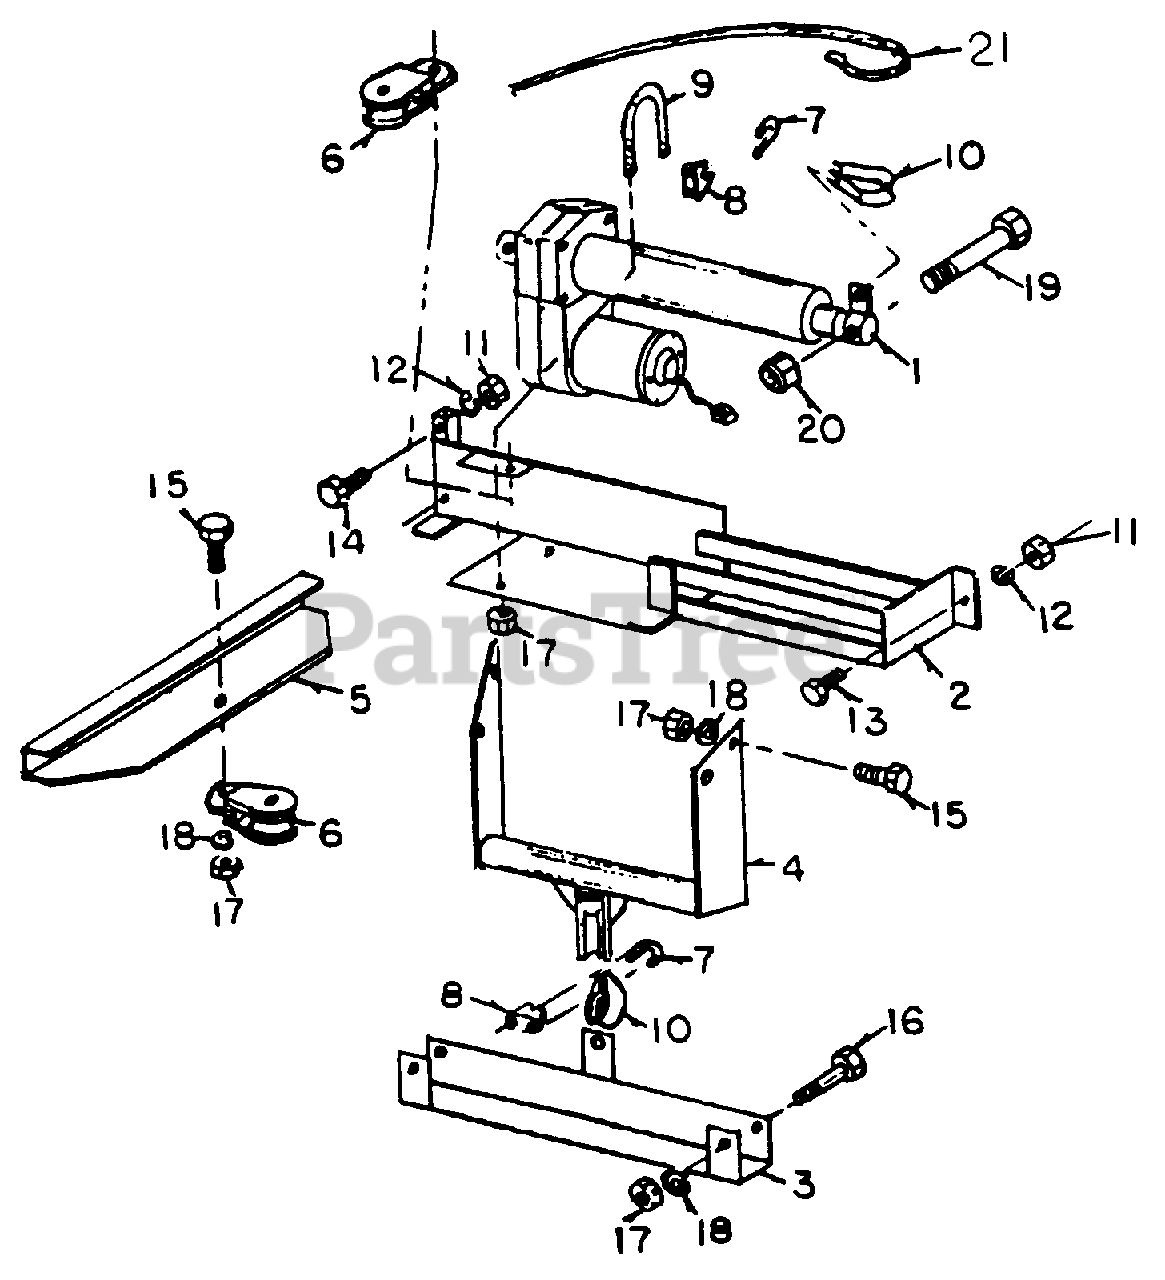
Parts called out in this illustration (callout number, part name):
2	Actuator Mount
3	Deck Lift Adapter
4	Cable Mount, Nose
5	Cable Mount, Side
7	U-bolt
9	U-bolt, Actuator
11	Hex Nut, 1/4-20
12	Lockwasher, 1/4"
13	Hex Capscrew, 1/4-20 x 3/4", GR5
14	Hex Capscrew, 1/4-20 x 1", GR5
15	Hex Capscrew, 5/16-18 x 1", GR5
16	Hex Capscrew, 5/16-18 x 2", GR5
17	Hex Nut, 5/16-18
18	Lockwasher, 5/16"
19	Actuator Bolt
20	Hex Locknut, 1/2-13
21	Cable, 3/16" x 64"
